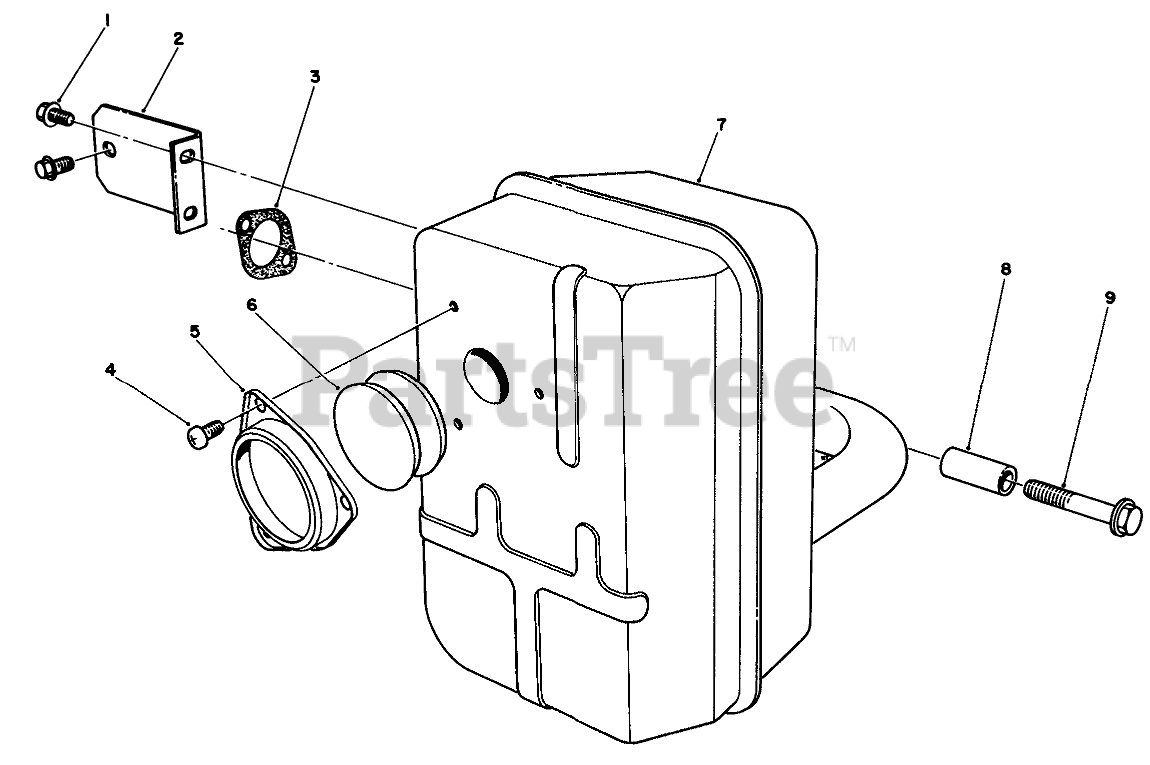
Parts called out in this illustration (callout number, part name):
1	Bolt-Flanged (8X12)
5	Cap
6	Arrester-Spark
7	Muffler ASM
9	Bolt-Flanged (8X45)
